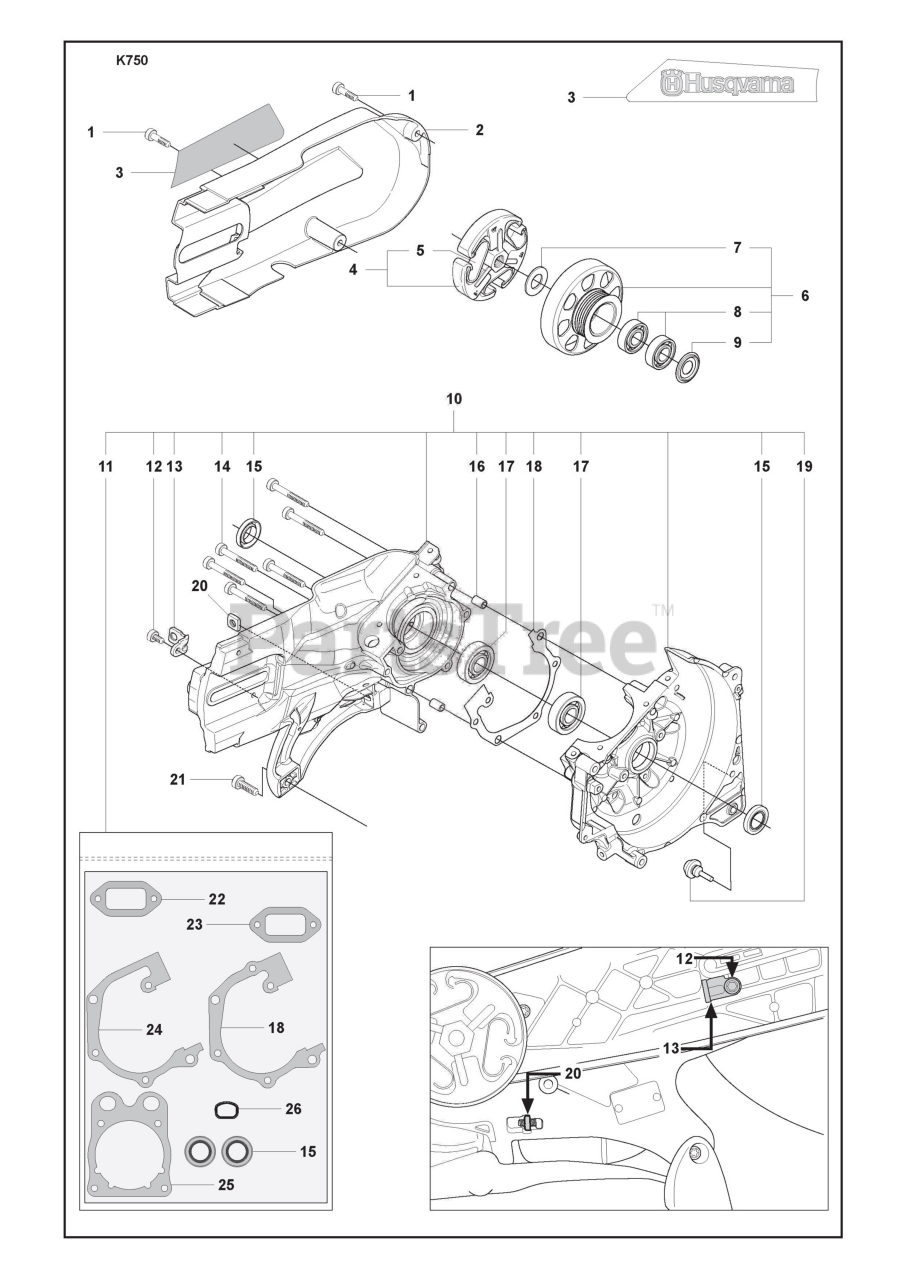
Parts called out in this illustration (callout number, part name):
2	BELT GUARD
4	CLUTCH ASSY
5	CLUTCH SPRING
6	DRIVING PULLEY ASSY
7	WASHER STEEL
8	BALL BEARING
9	DUST COVER
10	CRANKCASE ASSY
11	GASKET KIT
15	SEALING RING
16	GUIDE BUSHING
17	BALL BEARING
18	GASKET CRANKCASE
23	GASKET MUFFLER
24	GASKET CRANKCASE
25	CYLINDER BASE GASKET
